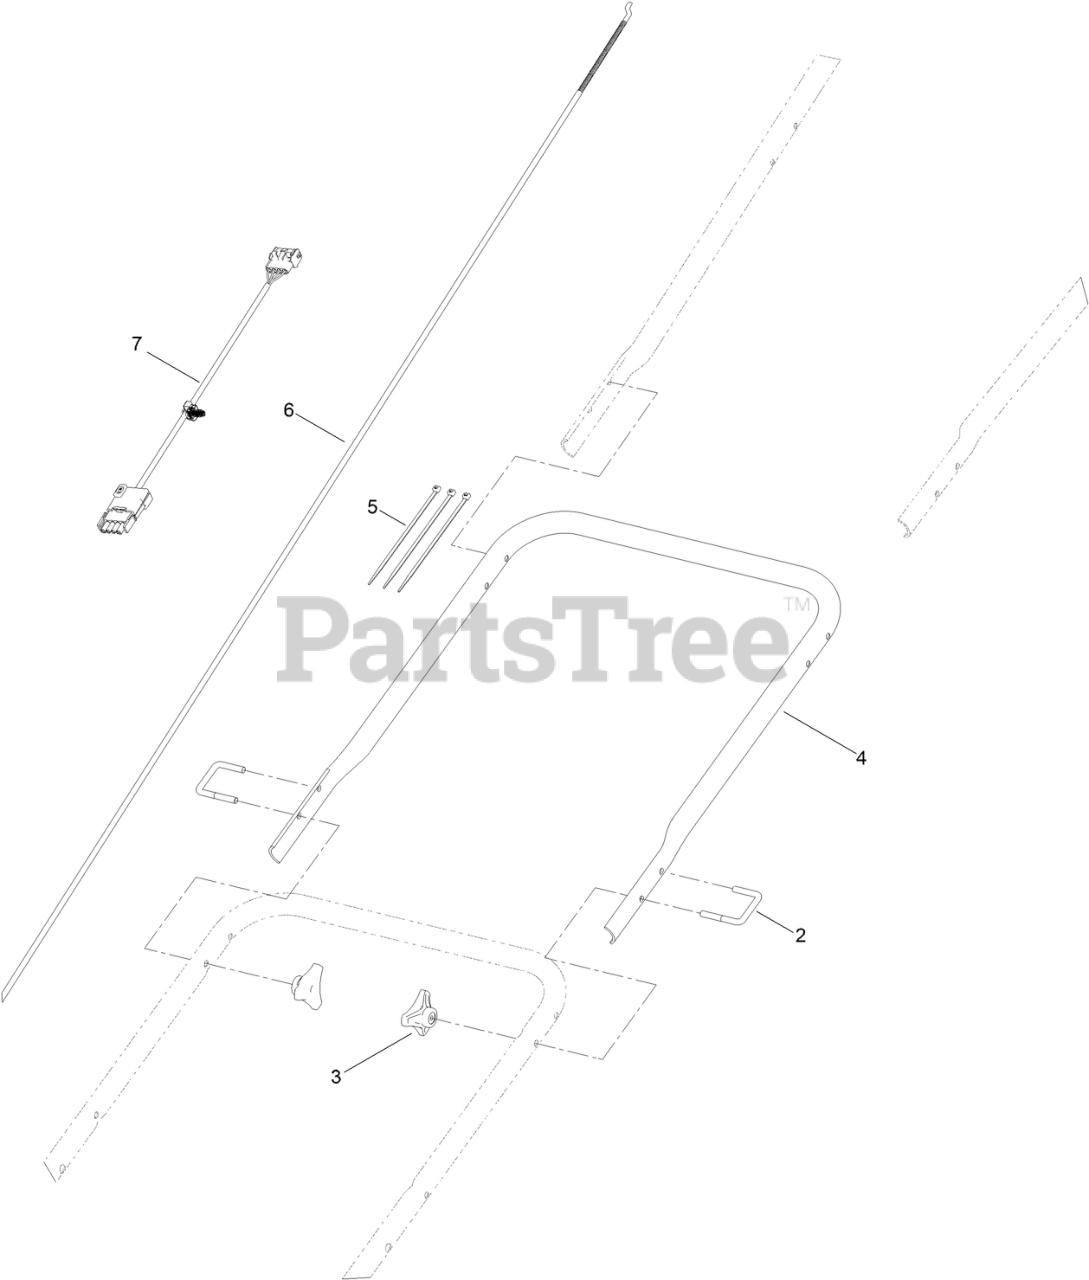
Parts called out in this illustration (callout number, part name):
2	BOLT-U
3	HANDWHEEL
4	EXTENSION-HANDLE
5	TIE-CABLE
6	OPC EHOVER, EXTENSION
7	LEAD-EXTENSION
